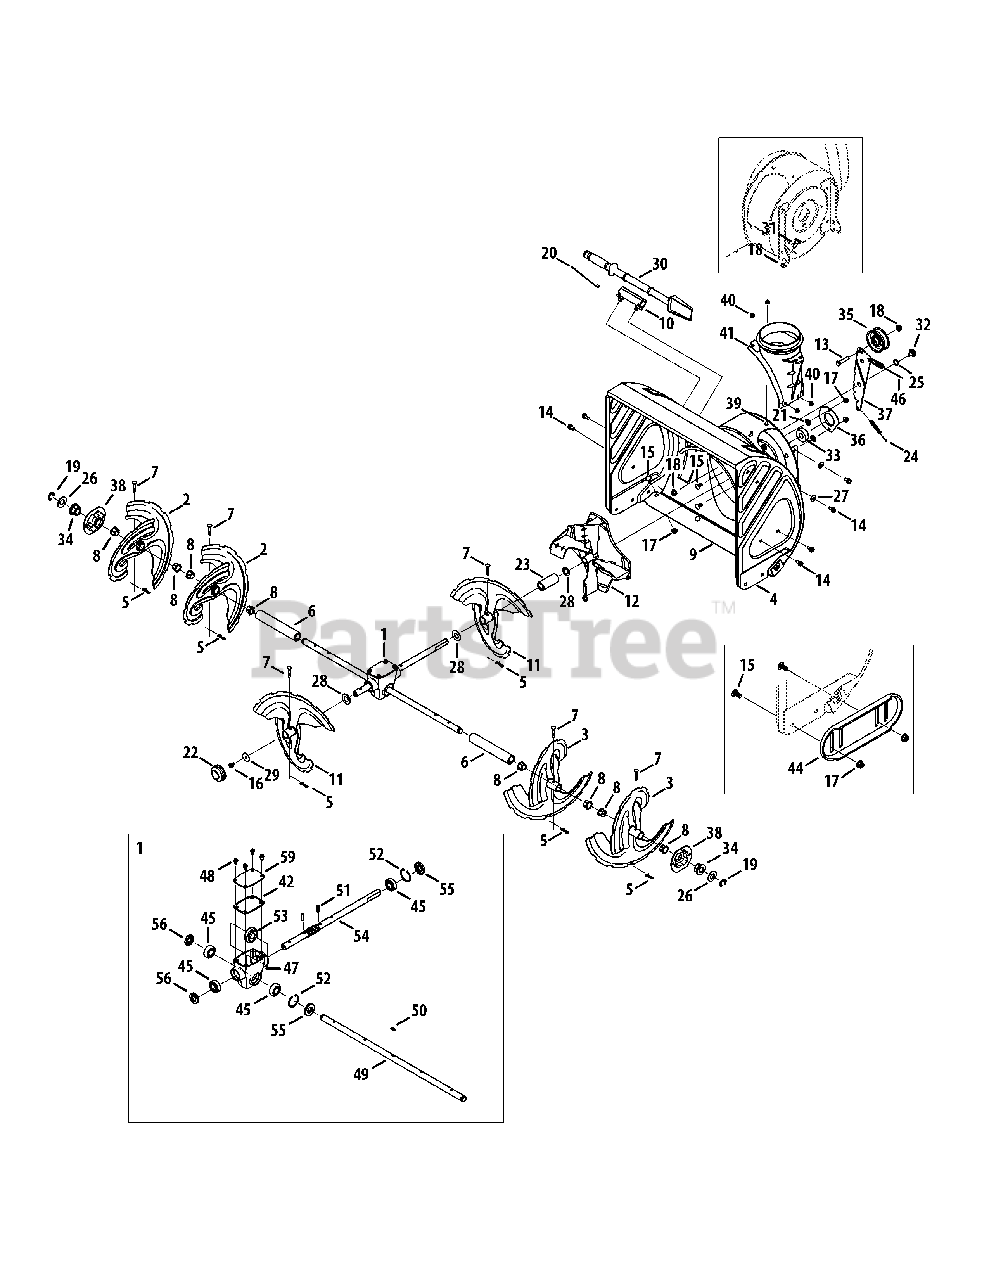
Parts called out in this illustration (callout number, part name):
1	Gearbox Assembly, Auger, 30"
2	Spiral Assembly - RH
3	Spiral Assembly - LH
4	Auger Housing, 30"
5	Bow Tie Cotter Pin
6	Spacer, 1.25 OD x .75 ID x 7.38
8	Flange Bushing, .800 x .910
9	Shave Plate, 30"
10	Clean-out Tool Mtg. Bracket
11	Accelerator Assembly
12	Impeller Assembly
13	Hex Bolt, 3/8-16 x 1.75
14	Screw, 5/16-18 x .750
15	Carriage Bolt, 5/16-18 x .750
16	Hex Washer Screw, 5/16-18 x .500
17	Flange Lock Nut, 5/16-18
18	Flange Lock Nut, 3/8-16
19	E-ring, .75
20	Cable Tie
21	Push-On Nut, .25 Dia.
23	Spacer, 1.35 OD x .76 ID x 2.755
24	Extension Spring, .38 OD x 4.59
25	Wave Washer, .625 x .885 x .0175
26	Flat Washer, .76 x 1.49 x .06
27	Bell Washer, .340 x .872 x .060
28	Flat Washer, .793 x 1.24 x .06
29	Flat Washer, .406 x 1.92 x .060
30	Clean-Out Tool
31	Shoulder Screw, 3/8-16 x .496 x .336
32	Shoulder Screw, 3/8-16 x .625 x .17
33	Flange Ball Bearing, .75 x 1.85
34	Hex Flange Bearing, .75 ID
35	Flat Idler Pulley
36	Bearing Housing
39	Carriage Screw, 1/4-20 x 0.75
40	Flange Lock Nut, 1/4-20
41	Chute Adapter
42	Gearbox Gasket
43	Gearbox Cover
44	Deluxe Slide Shoe
45	Ball Bearing, .75 x 40 x 12
46	Auger Clutch Cable
47	Auger Housing
48	Screw, 1/4-20 x 0.75
49	Axle, Auger, 30"
50	Hi-Pro Key
51	Pin, Roll, .25 x 1.0
52	Retainer Ring
53	Worm Gear, 20T
54	Worm Shaft
55	Seal, .75 x 40mm x .25
56	Seal, .75 x 1.375 x .25
